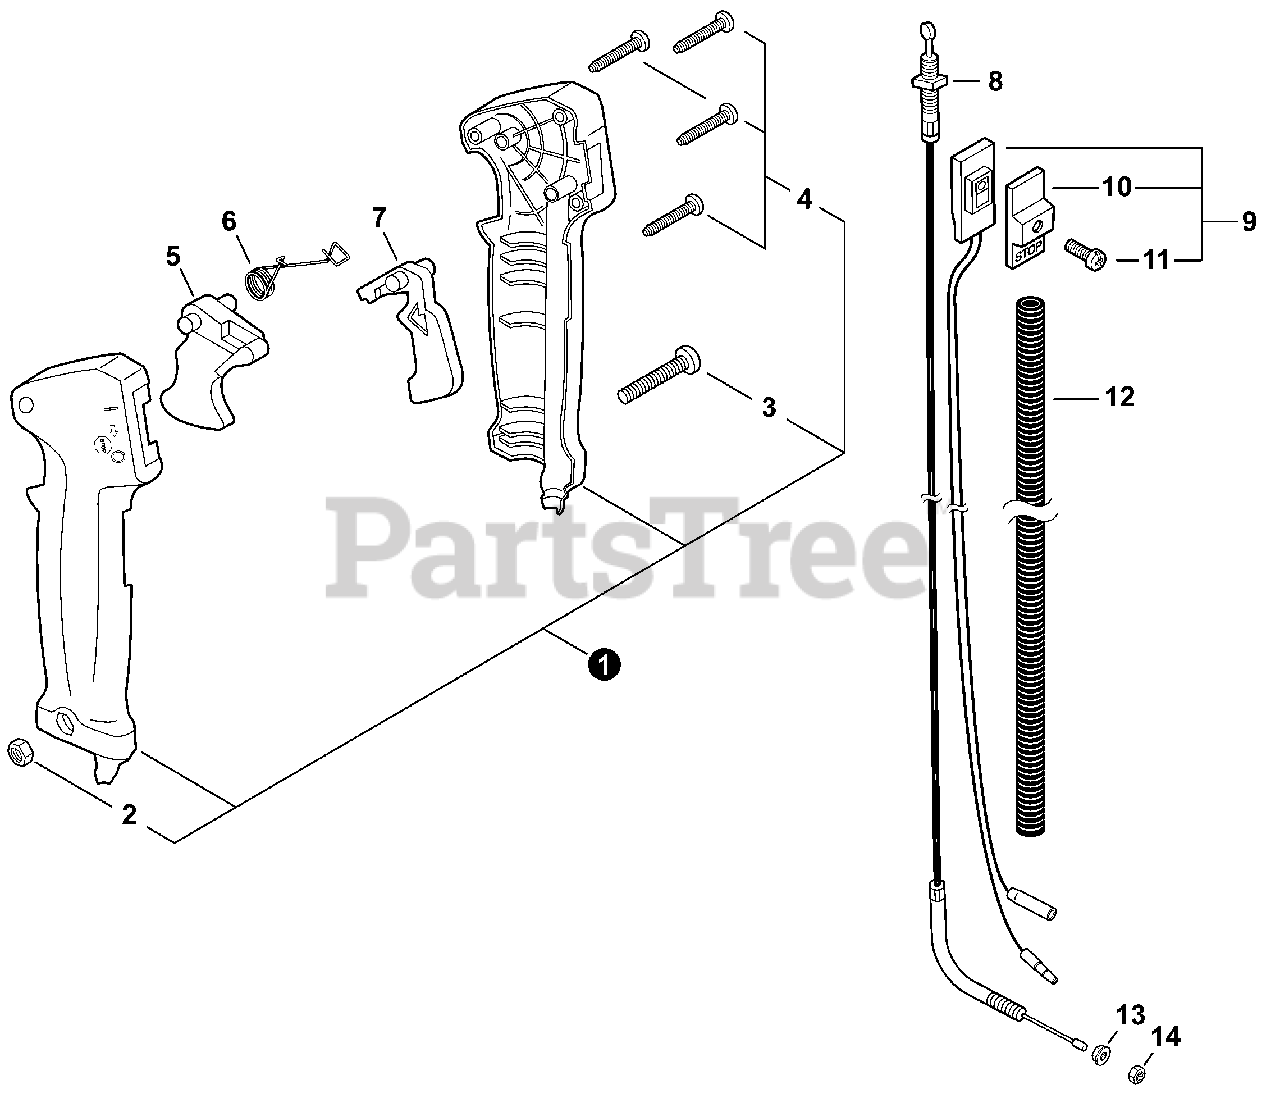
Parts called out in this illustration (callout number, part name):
1	CONTROL HANDLE KIT
2	NUT M5
3	SCREW 5×30
4	SCREW 3×25
5	TRIGGER, THROTTLE
6	SPRING, TORSION
7	LOCKOUT, THROTTLE
8	CABLE, THROTTLE
9	SWITCH, ON-OFF
10	KNOB, SWITCH - ORANGE
11	SCREW 3×10
12	TUBE, FLEXIBLE 7×790
13	NUT, FLANGE M6
